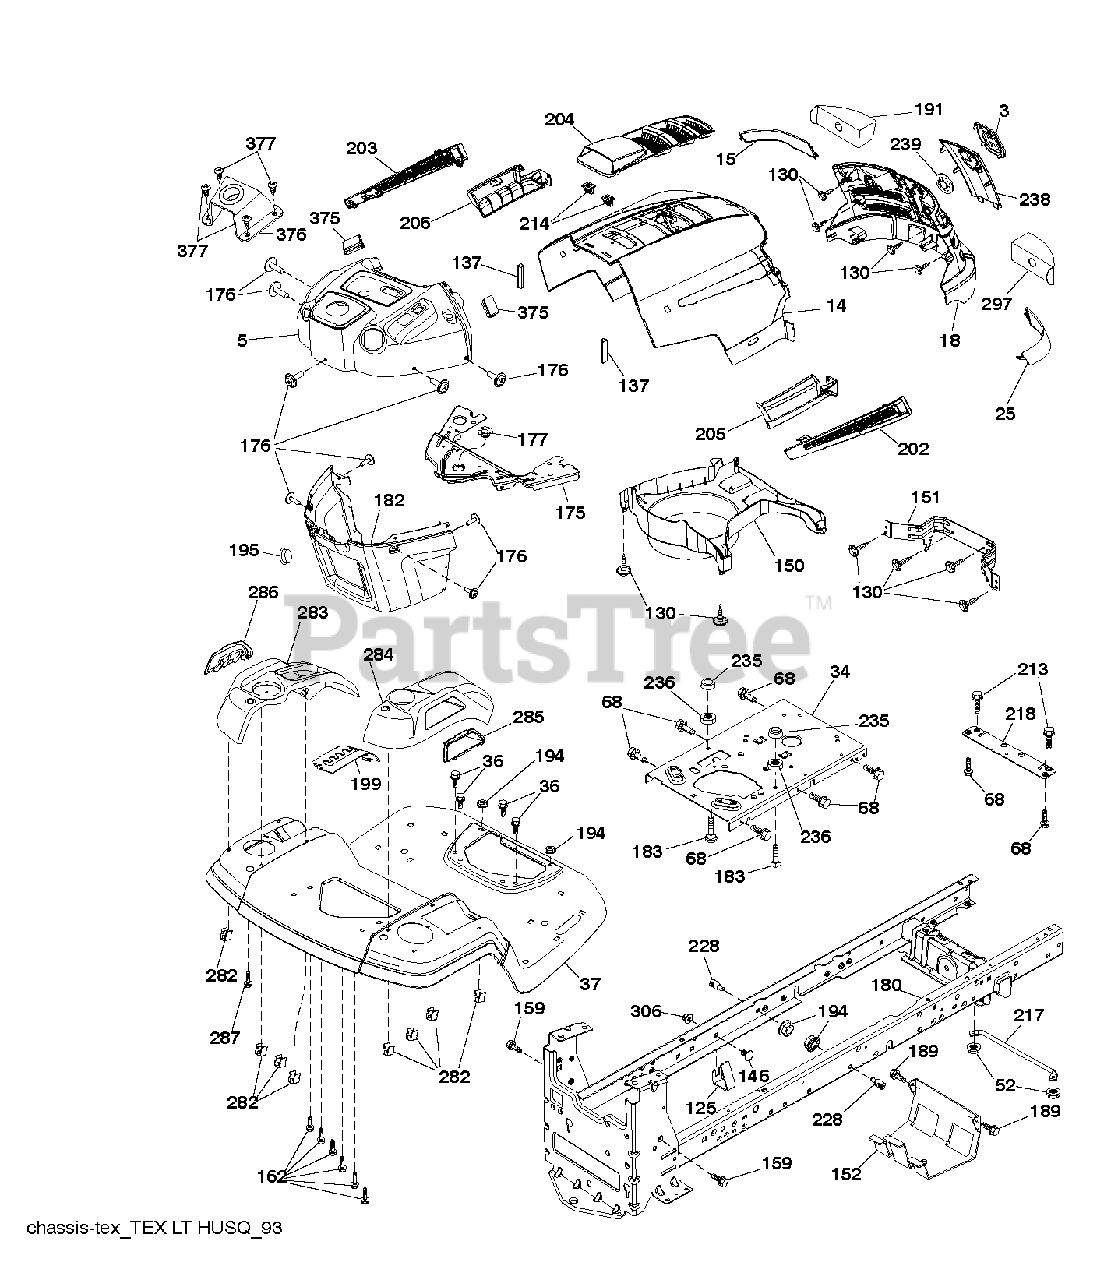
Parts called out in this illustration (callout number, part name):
3	LOGO.HUSQ.GT.LT.CROWN.H
5	DASH.UPPER.HUSQ.LT.MAN.NO-CHK
14	HOOD.HUSQVARNA.LT.ORANGE
15	LENS.HUSQVARNA LT.RH
18	GRILLE.SVC.HUSQVARNA.GREY
25	LENS.HUSQVARNA LT.RH
34	PLATE.ENGINE.WELDED.CHASSIS
36	SCREW 5/16"
37	FENDER.TLT.FS.W/CUPHLD.ORANGE
52	LOCKNUT
68	SCR 5/16-18 X 1/2 SELFTAP ZN
125	CLIP.FUEL.LINE
130	SCREW.#10 X 0.750.BOS
137	BUMPER DASH
146	BOLT.RDHD.SHT.SQNK.3/8-16X5/8
151	BRACKET PIVOT
152	SHIELD.BROWNING.W/TEX
159	SCREW, 3/8-16X3/4
162	SCREW.HI-LO.CONSOLE
175	CROSSMEMBER
176	SCREW.#10-24X5/8.RN.QU
177	BUSHING STEERING
180	CHASSIS
182	DASH.LOWER.PREDATOR LT
183	BOLT.5/16-18X1-1/4 FULL THD
189	SCREW
191	INSERT.REFLECTIVE.RH.
194	NUT LOCK HEX FLANGE 5/16-18
195	PLUG.TEX.DASH.SVC.MINDER.GREY
199	PLATE.DECK.LIFT.HUSQ.LT
202	VENT.SIDE.HUSQVARNA.LT.RT
203	VENT.SIDE.HUSQVARNA.LT.LFT
204	SUBASM.TOP.VENT.HUSQ.LT
205	SKIRT.SIDE.HUSQVARNA.LT.RT
206	SKIRT.SIDE.HUSQVARNA.LT.LEFT
213	BOLT
214	CLIP.RETAINER.TINNER.
217	ROD.PIVOT.HOOD
218	X-PIECE.HOOD.STOP.NON/
228	STUD.FASTNER.W/ANTI-ROTATE
235	SPACER FENDER
236	NUT.CENTERLOCK.5/16-
238	TRIM.HUSQ LT.668
282	CLIP.RETAINER.CONSOLE.LT.HUSQ
283	CONSOLE LT DECKLIFT CONSOLE
284	CONSOLE CONSOLE.HUSQ.SHIFT.HYD
285	CONSOLE INSERT RH
286	CONSOLE.INSRT.LH.HUSQ.LT.BLACK
287	SCREW 1/4X20
297	INSERT REFLECTIVE
306	NUT LOCK FLG 3/8-16 UNC
375	BUMPER CLIP-ON. DASH 1"
376	MOUNT.ASM.HUSLT.UPPER.STRNG
377	SCREW 10 X 1/2 ZN PL PHIL PAN
